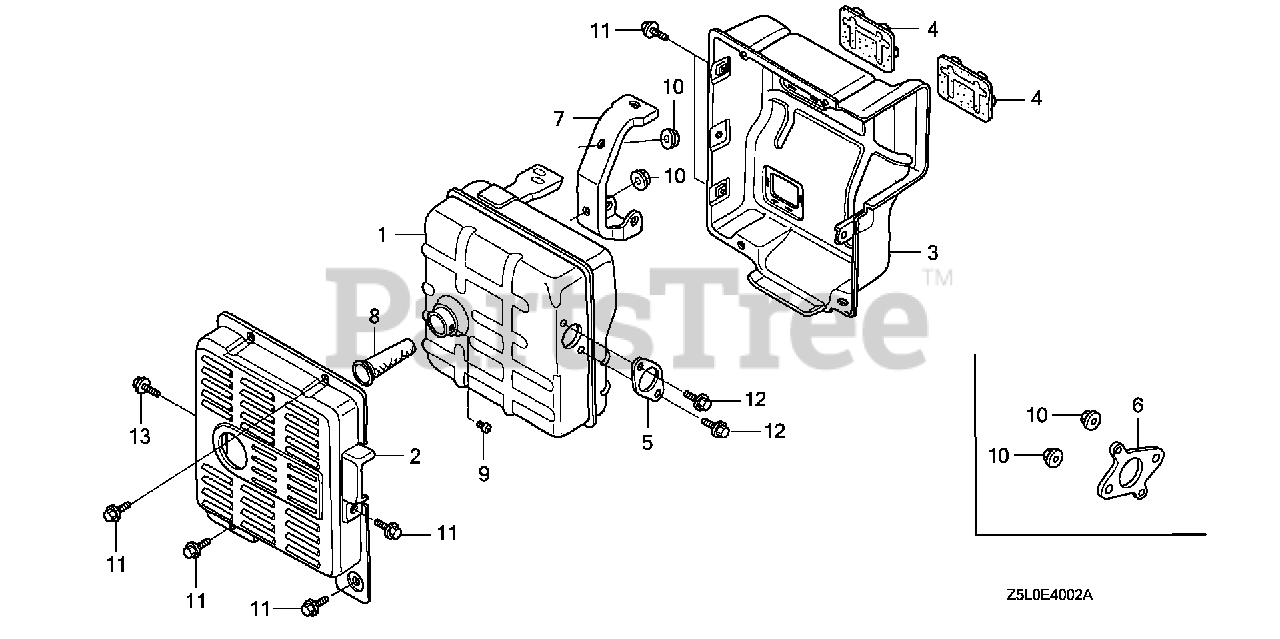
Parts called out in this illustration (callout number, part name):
1	MUFFLER (TSURUMI)
3	PROTECTOR, MUFFLER (INNER)
4	SEAL, MUFFLER PROTECTOR
5	GASKET, EX. PIPE
8	ARRESTER, SPARK
9	SCREW, TAPPING (4X8)
10	NUT, FLANGE (8MM)
12	BOLT, FLANGE (8X20) Use up to Engine SN 1609606.
